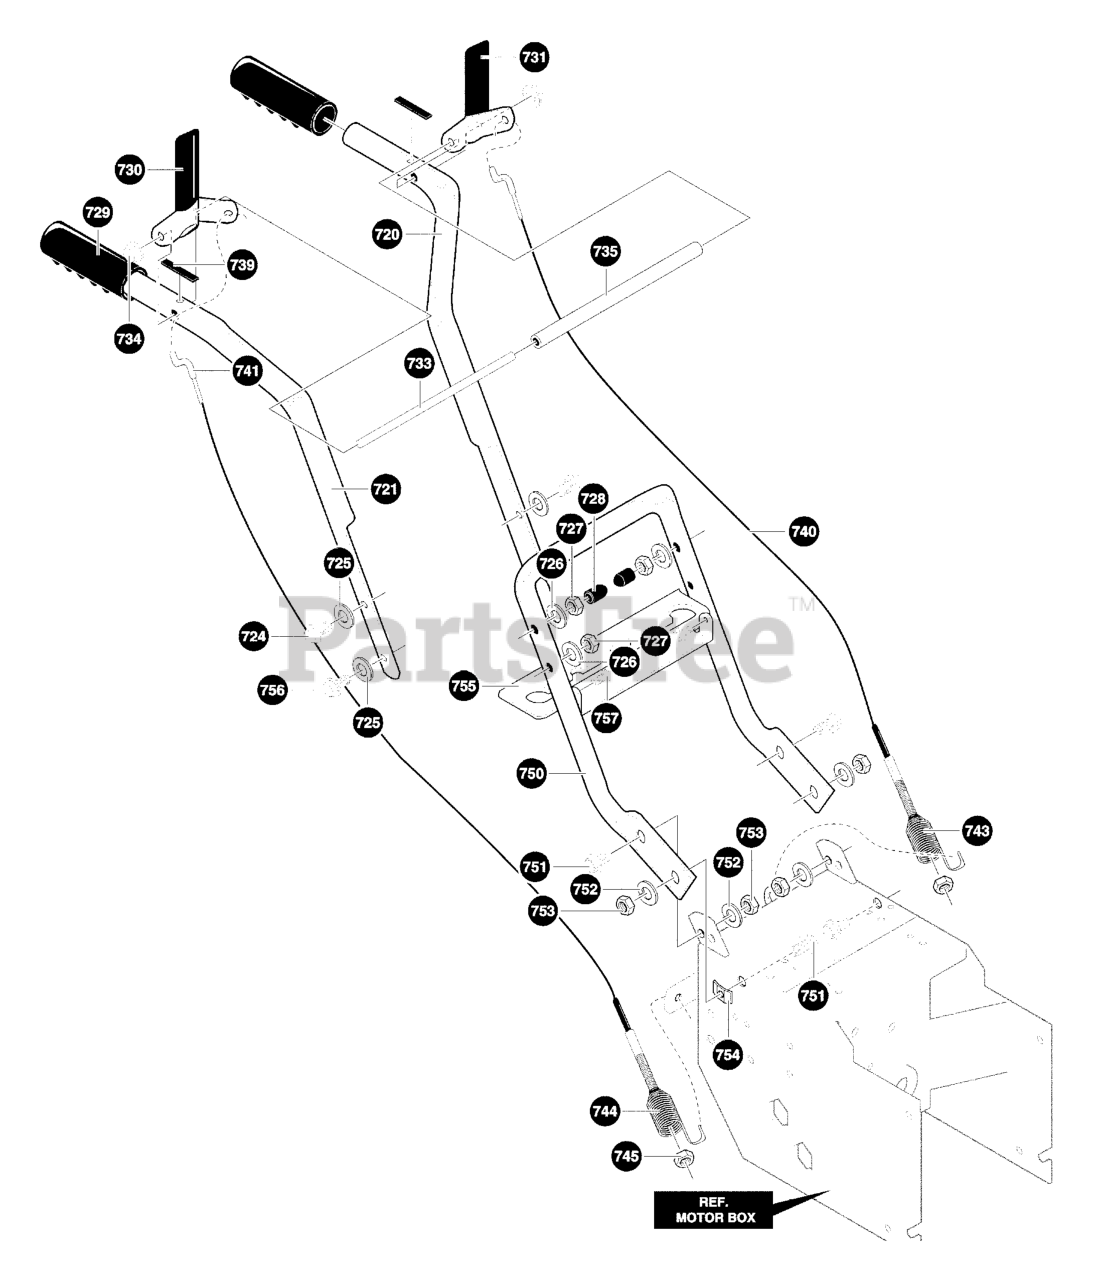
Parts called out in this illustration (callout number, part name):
720	HANDLE, UPPER LH
721	HANDLE, UPPER RH
724	SCREW, 5/16-18 x 2.75
725	WASHER, FLAT .349X.69X.066
726	WASHER, SPTLK .31X.58X.08
727	NUT, 5/16-18 REGHEX
728	STOP, RED PLASTIC
729	GRIP-HANDLE FINGER
730	LEVER, ASSY CLUTCH DRIVE RH
731	LEVER, ASSY CLUTCH DRIVE LH
733	ROD, PIVOT CLUTCH
734	NUT, PUSH ON CAP
735	SPACER-HANDLE
739	BUMPER, RECTANGLE
740	CABLE, CLUTCH 28.44L
741	CABLE, AUGER CLUTCH
743	TENSION SPRING
744	SPRING, AUGER CLUTCH
745	NUT, 1/4-20
750	HANDLE, LOWER
751	CAPSCREW, Hex Head, 5/16-18 x 1
752	WASHER, SPTLK
753	NUT, 5/16-18 REGHEX
754	PUSHNUT, 5/16 BOLT RETAINER
755	BRKT, GEAR SELECTOR
756	SCREW, 5/16-18 x 2.00
757	SCREW, .25X.75X.51
